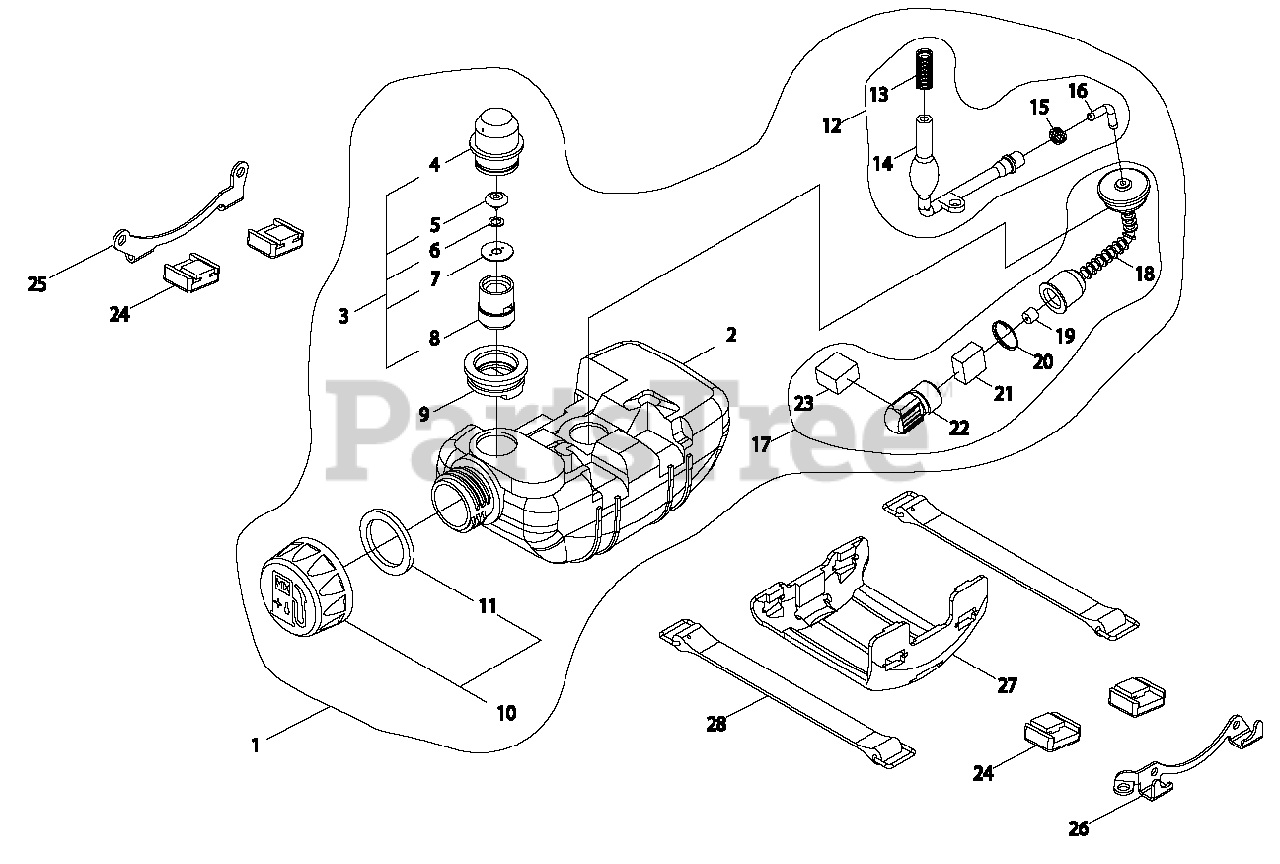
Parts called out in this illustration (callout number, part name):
1	TANK ASSY, FUEL
2	TANK, FUEL
3	VENT ASSY
4	CAP, VENT
5	VENT ASSY
6	WASHER
7	RETAINER
8	HOLDER, VENT
9	GROMMET
10	CAP ASSY, FUEL
11	GASKET, FUEL CAP
12	PIPE ASSY, FUEL
13	CLAMP
14	PIPE, FUEL
15	CLIP
16	CONNECTOR, PIPE
17	FILTER ASSY, FUEL
18	PIPE, FUEL
19	VALVE, CHECK
20	CLIP
21	FILTER, FUEL - B
22	WEIGHT
23	FILTER, FUEL - A
24	CUSHION, FUEL TANK
25	BRACKET M
26	BRACKET S
27	GUARD, FUEL TANK
28	STRAP, FUEL TANK
